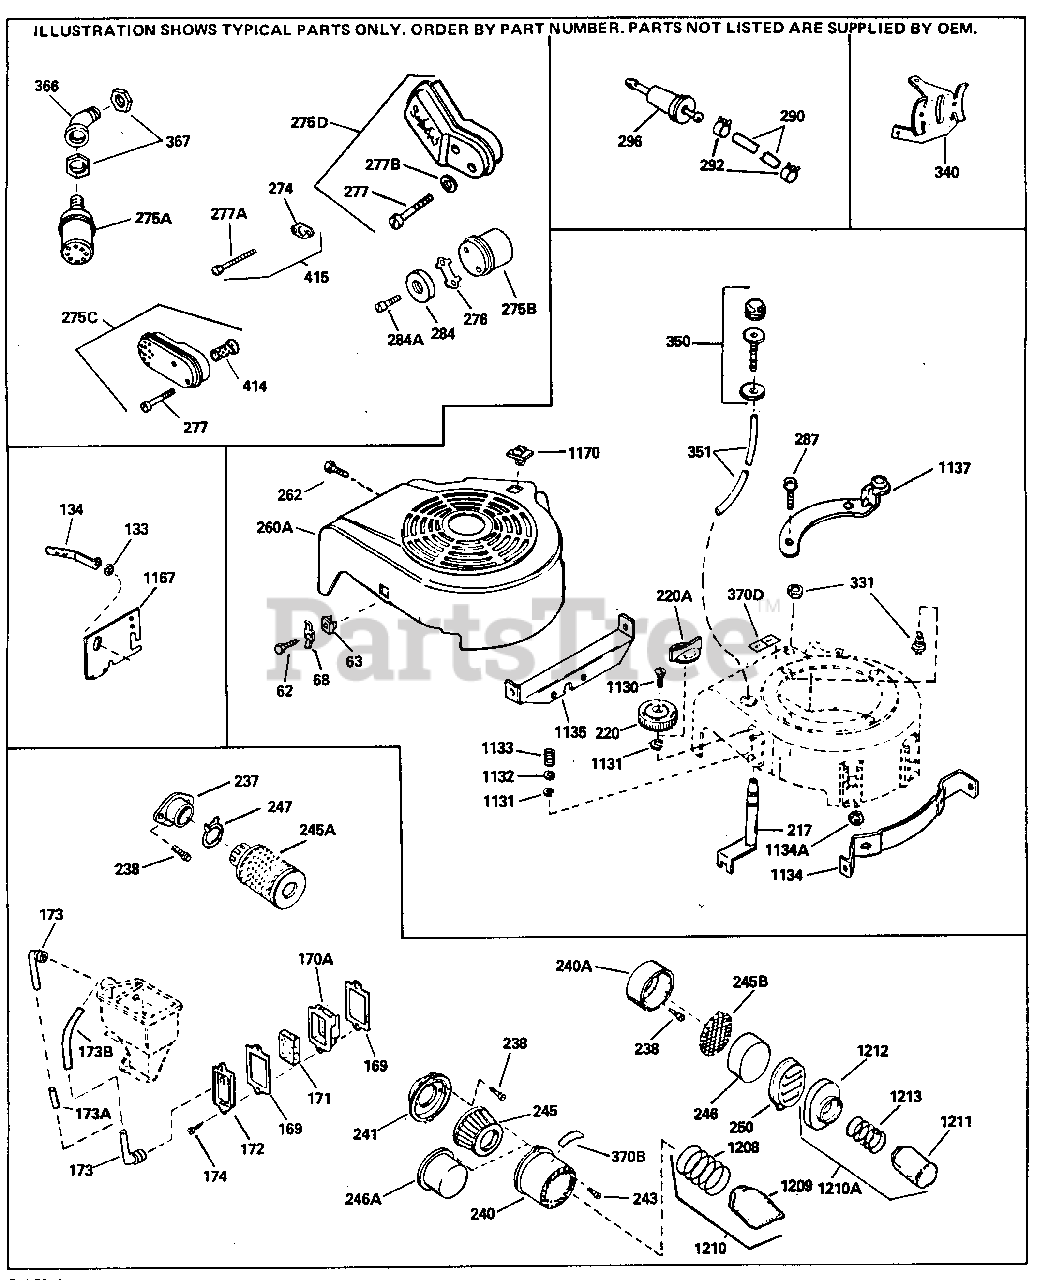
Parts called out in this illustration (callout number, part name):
19	Spring, Governor
167	Spring, Speed adj. screw
168	Screw, 10-32 x 1"
169	* Gasket, Valve spring cover
171	Element, Breather
174	Screw, 10-24 x 1/2"
182	Screw, 1/4-28 x 7/8"
238	Screw, 10-32 x 5/8"
243	Screw, 8-32 x 3/8"
262	Screw, 1/4-20 x 5/8"
274	* Gasket, Exhaust
277	Screw, T-30, 1/4-20 x 1/2" as req.)
277A	Screw, 1/4-20 x 2-3/8"
287	Screw, 1/4-28 x 7/16" Use as require d
287	Screw & Lockwasher, 1/4-28 x 1/2"
287	Pop Rivet (Purchase locally) 3/16" di a.
290	Fuel Line (8.62") as req.)
290	Fuel Line (Braided 16")(40 cm) Use as req.
290	Fuel Line (Epichlorohydrin 6-3/4") 1 7 cm
292	Fuel Line Clamp
415	Muffler Adapter Kit (Incl. 274 & 277A ) (Inverted Ports)
